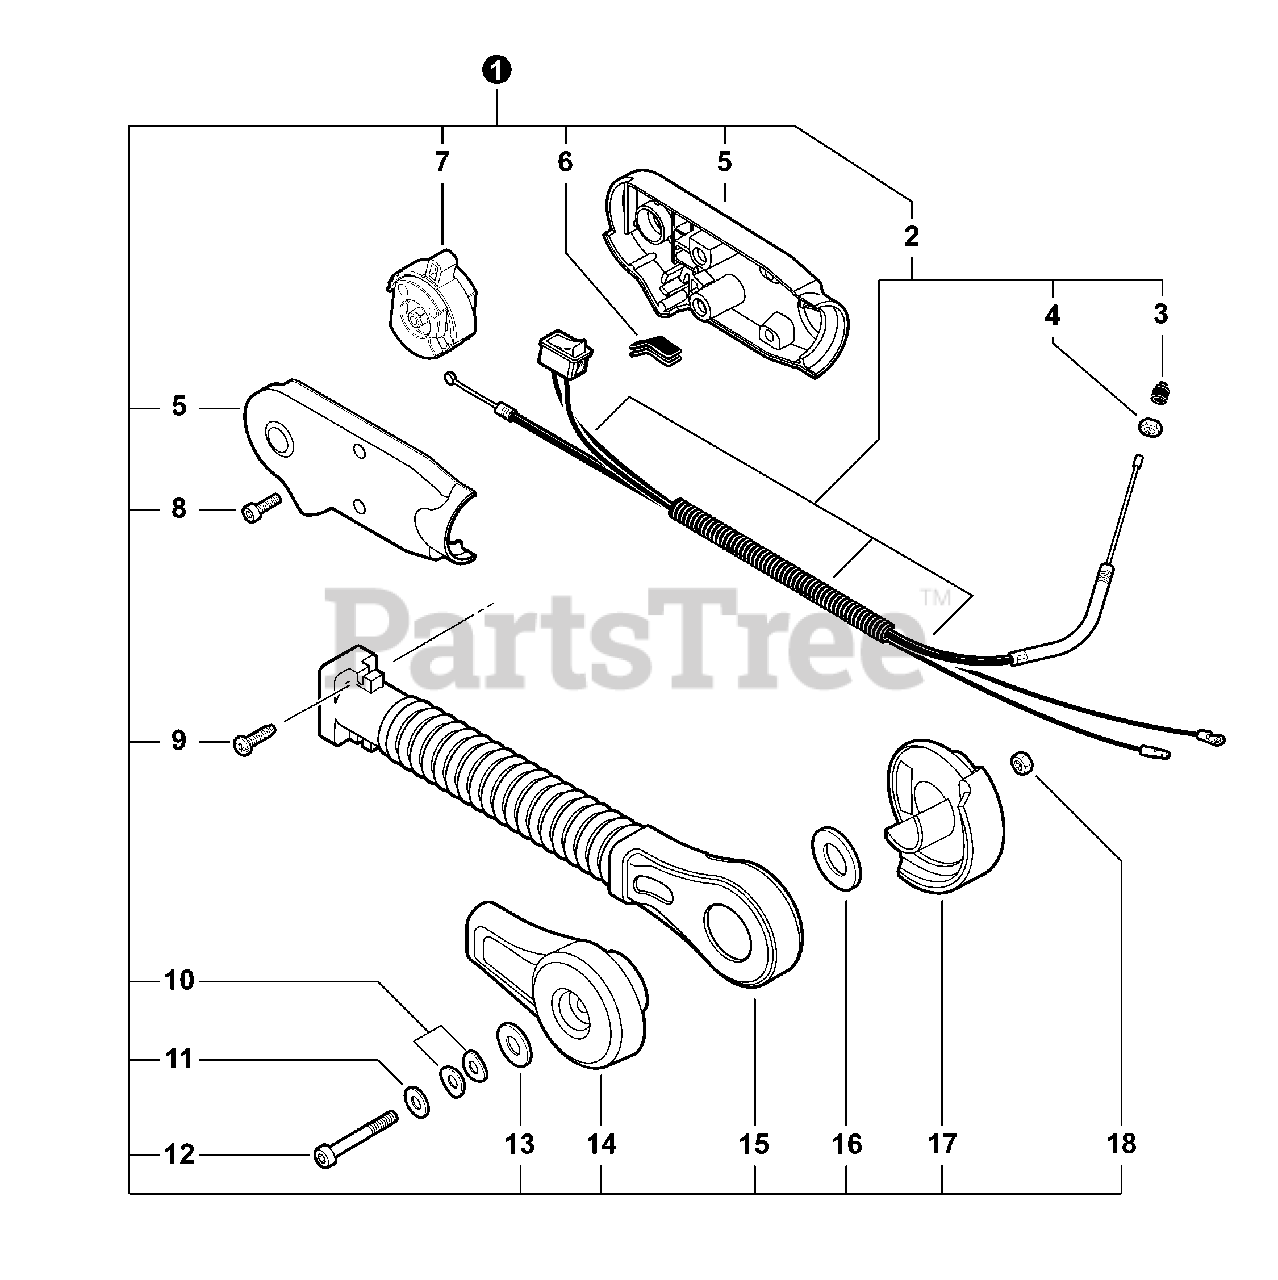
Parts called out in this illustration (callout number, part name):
1	THROTTLE CONTROL KIT - HIP MOUNT
2	CABLE ASSY, CONTROL
3	CAP, DUST
4	NUT, HEX M6
5	GRIP SET, THROTTLE
6	GROMMET
7	THROTTLE CONTROL ASSY
8	BOLT, TORX 5×16
10	WASHER, FRICTION 6.6×14.3
11	WASHER 6.6×20×1.6
12	BOLT, TORX 6×75
13	WASHER 6.5×15.5×0.6
14	BRACKET, ARM - OUTER
15	ARM, THROTTLE CONTROL
16	WASHER 45
17	BRACKET, ARM - INNER
18	NUT, LOCK M6
